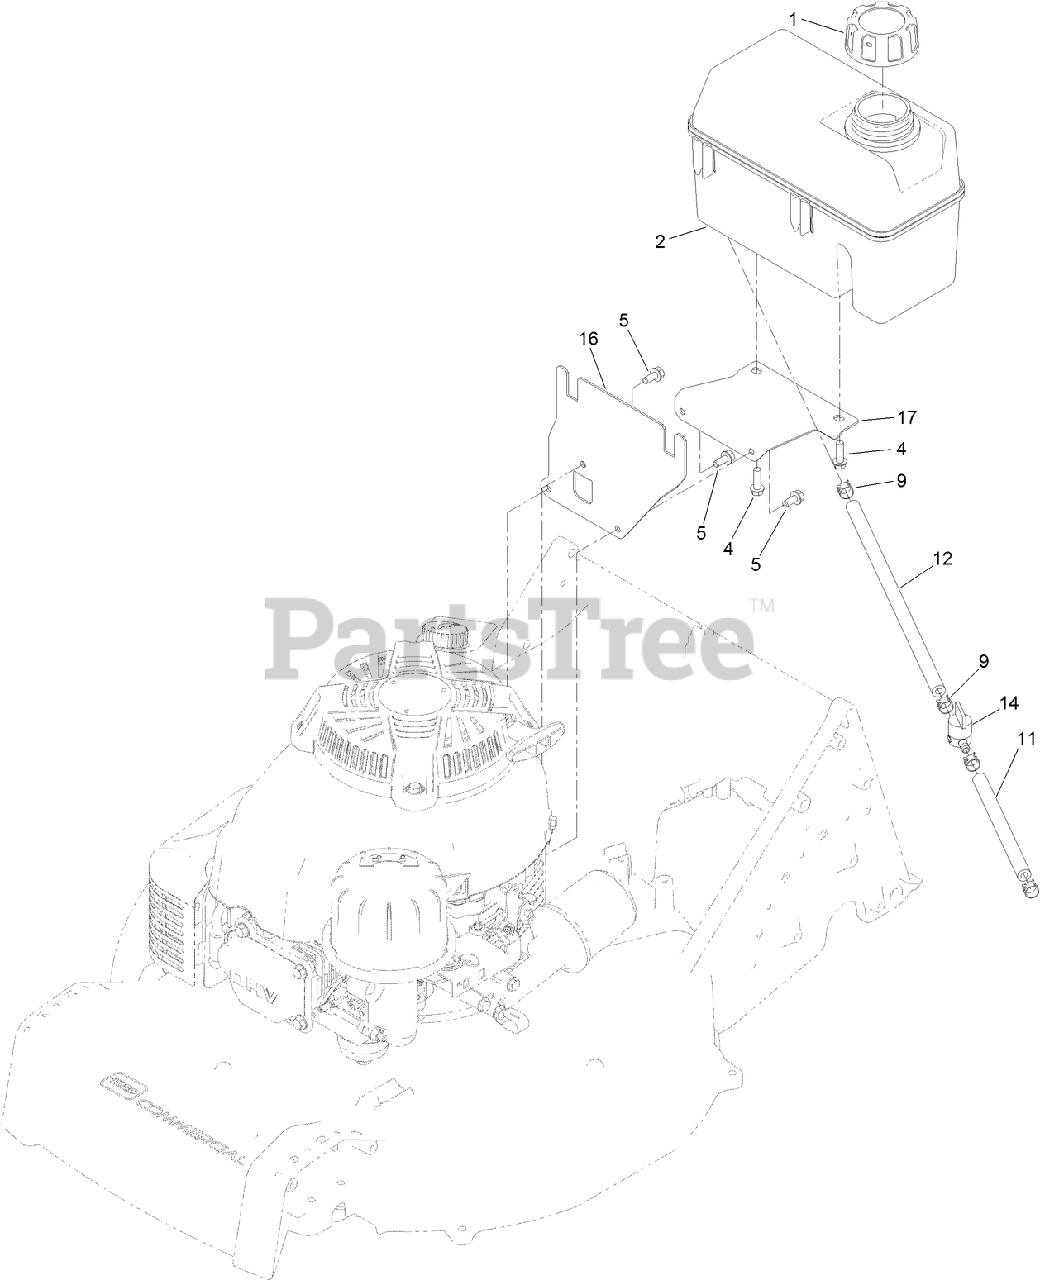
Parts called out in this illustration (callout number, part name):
1	CAP-GAS
2	TANK-FUEL
4	SCREW-HWH
5	SCREW-HWH
9	CLAMP-HOSE
11	HOSE-FUEL
12	HOSE-FUEL
14	VALVE-FUEL
16	BRACKET-TANK, MOUNTING
17	BRACKET-TANK, SUPPORT
